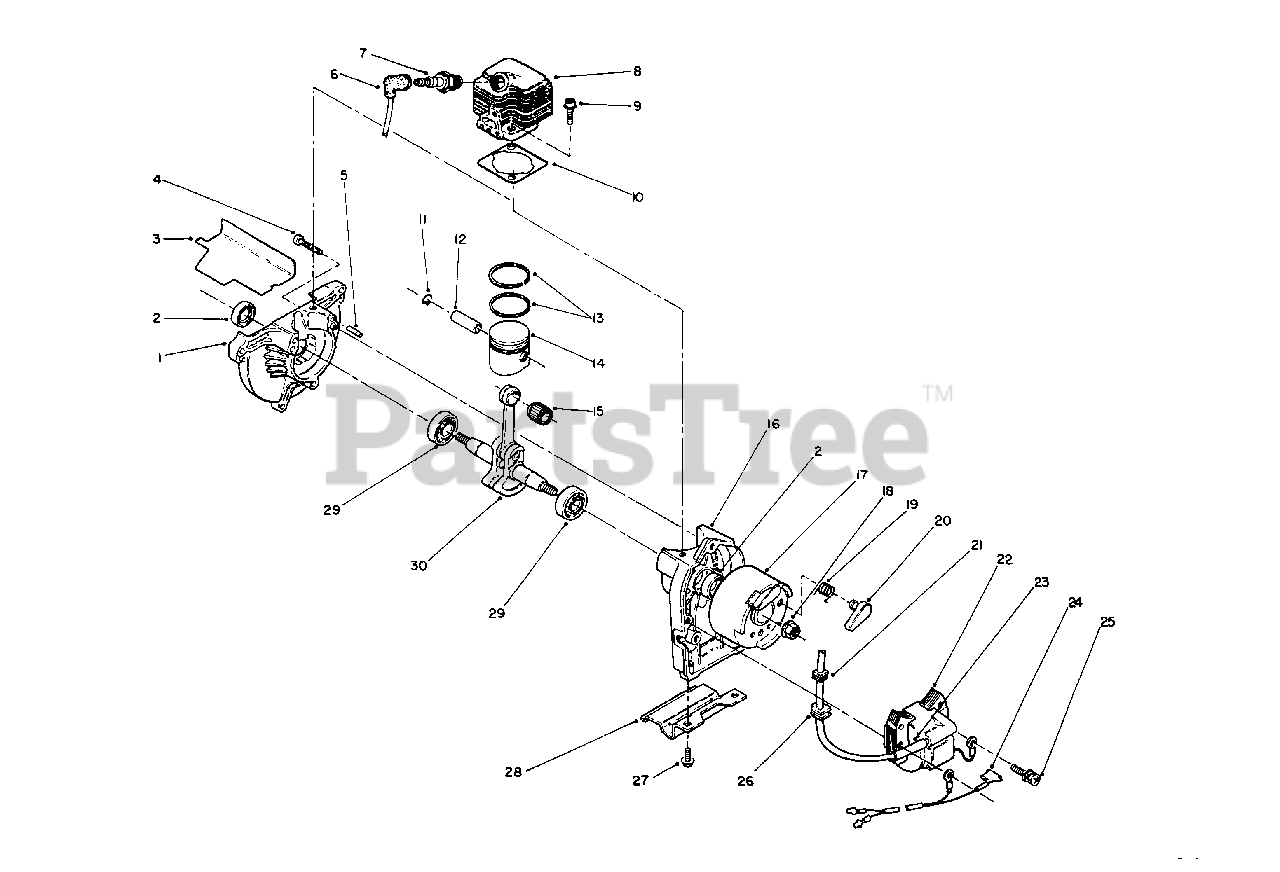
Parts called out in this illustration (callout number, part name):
1	Case-Drive
2	Seal-Oil
3	Gasket-Insulator
4	Screw-Pan Hd.
5	Pin-Dowel
6	Boot-Plug
7	Plug-Spark
8	Cylinder Head
9	Bolt-Cylinder Head
10	Gasket-Cylinder Head
11	Clip-Piston Pin
12	Pin-Piston
13	Set-Piston Ring
14	Piston Assembly (Incl. Ref. #12)
15	Bearing-Needle
16	Case-Starter
17	Flywheel Assembly (Incl. Ref. #19 & 20)
18	Nut-Conical
19	Spring-Return
22	Coil-Ignition
23	Tube-Insulator
24	Wire Assembly
25	Bolt/Washer
27	Screw/Washer
29	Bearing-Main
30	Crankshaft Assembly
